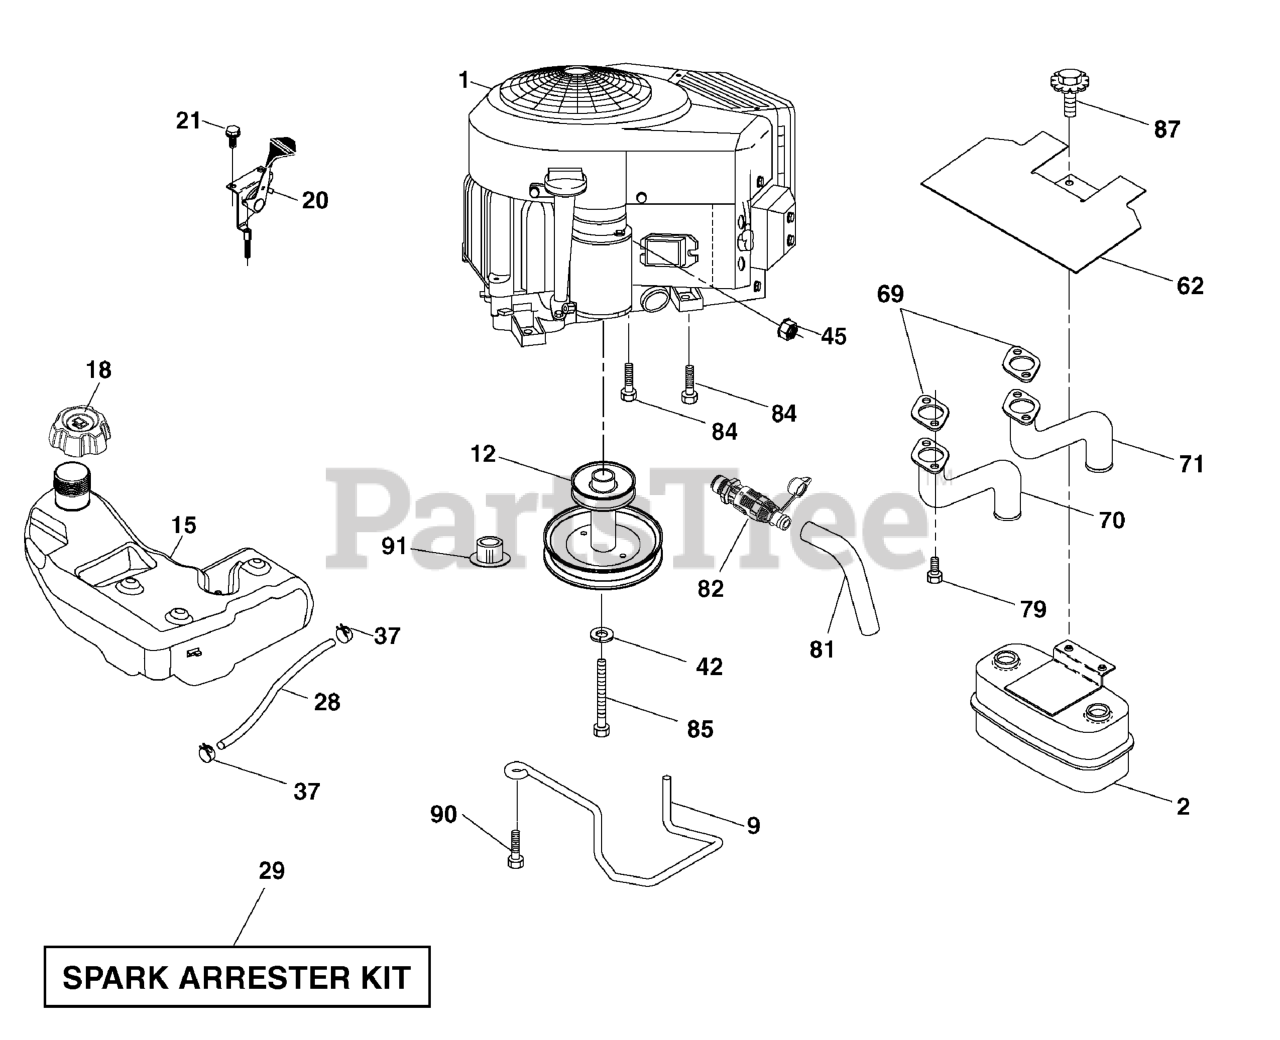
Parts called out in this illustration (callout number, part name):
1	* Engine, Briggs & Stratton
2	Muffler
9	Keeper Belt Engine
12	Pulley Engine
15	Tank Fuel
18	Cap Asm
20	Control Throttle/Choke
21	Screw #10 x 0.750
28	Fuel Line
29	Spark Arrester Kit
37	Clamp Hose
42	Washer Lock 7/16
45	Nut Keps Hex 1/4-20 unc
62	Shield Heat Muffler
69	Gasket
70	Exhaust Tube LH
71	Exhaust Tube RH
79	Screw Socket Hd 5/16-18 x 1
81	Tube Drain Oil Easy
82	Valve Drain Oil
84	Screw 3/8-16 x 1-1/4
85	Bolt Hex 7/16-20 x 4 x Gr. 5-1.5
87	Bolt 5/16-18 unc x 3/4
90	Screw 3/8-16 x 1.0
91	Bushing
